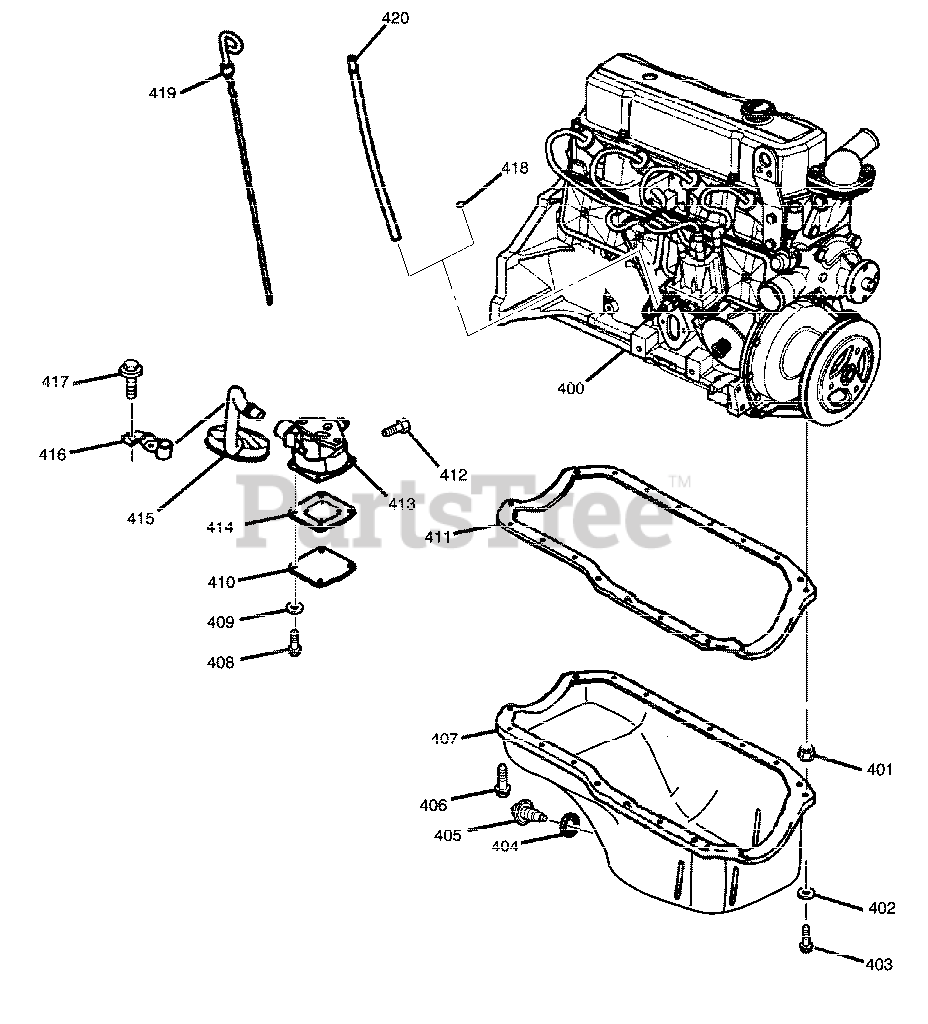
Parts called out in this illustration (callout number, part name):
401	* NUT
402	* WASHER
403	* BOLT
404	* GASKET
405	* PLUG (PART OF 407)
406	* BOLT
407	* PAN
408	* BOLT
409	* WASHER
410	* COVER
412	* BOLT
413	PUMP
414	* GASKET
416	* BRACKET
417	* BOLT
418	* PLUG
